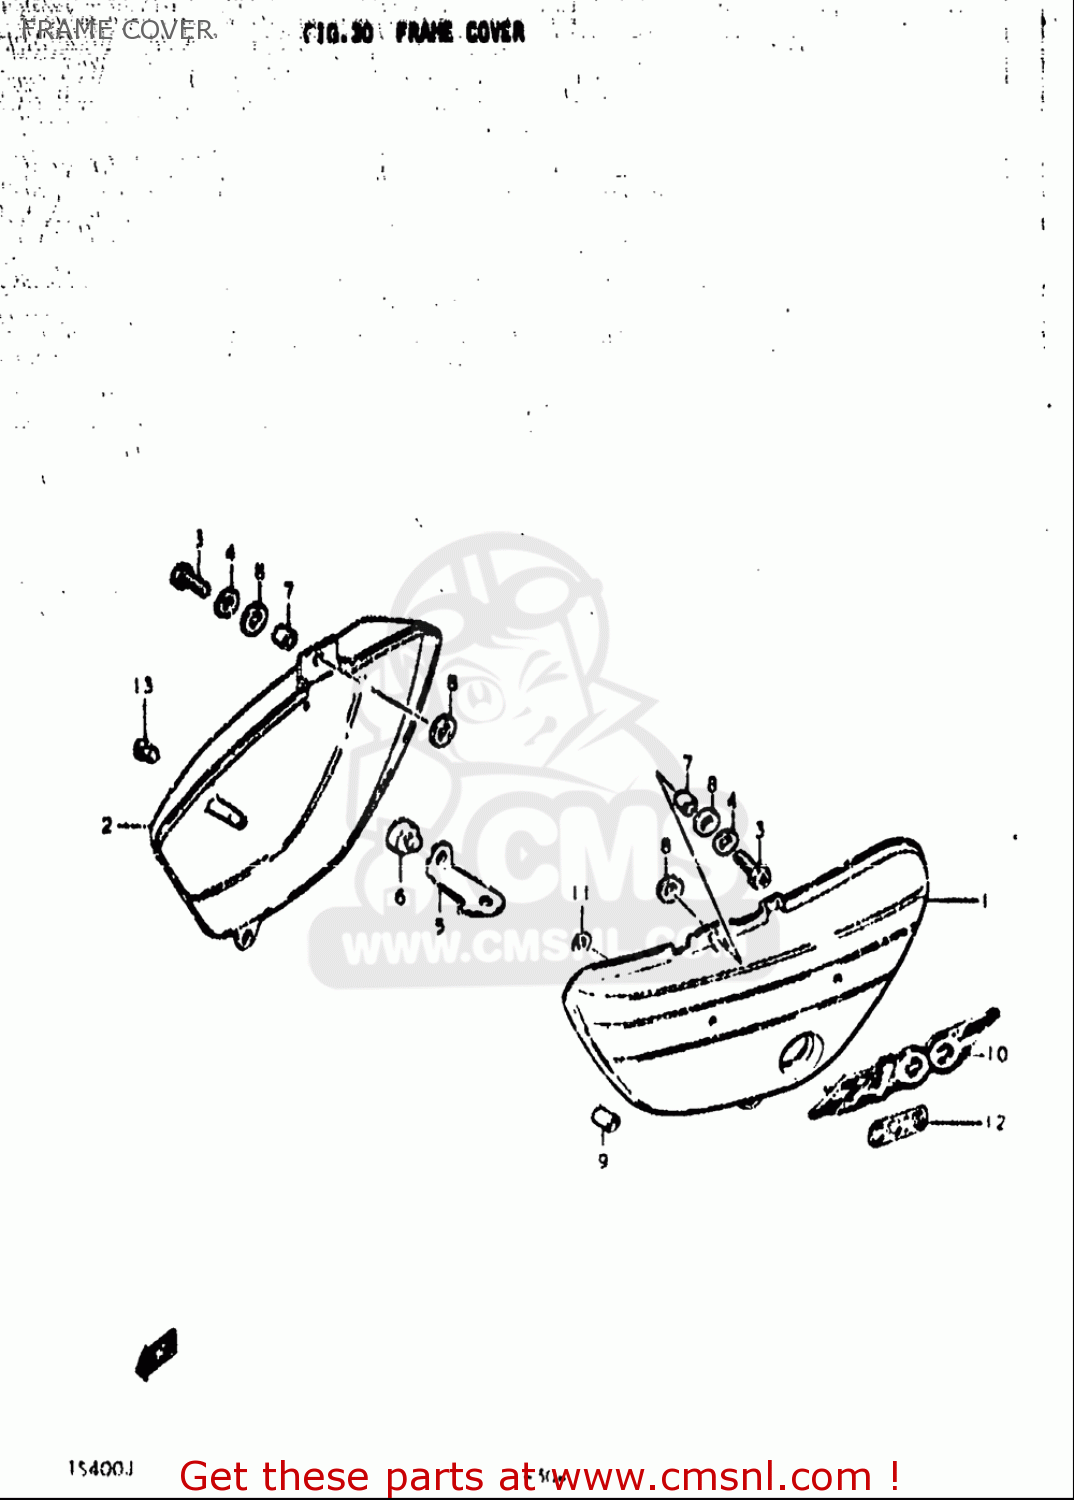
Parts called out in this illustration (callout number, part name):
3	SCREW
4	WASHER
7	SPACER(6.1X8X9.5)
8	CUSHION
9	CUSHION
11	NUT
12	EMBLEM,CCIS
13	CAP(OD:14)
